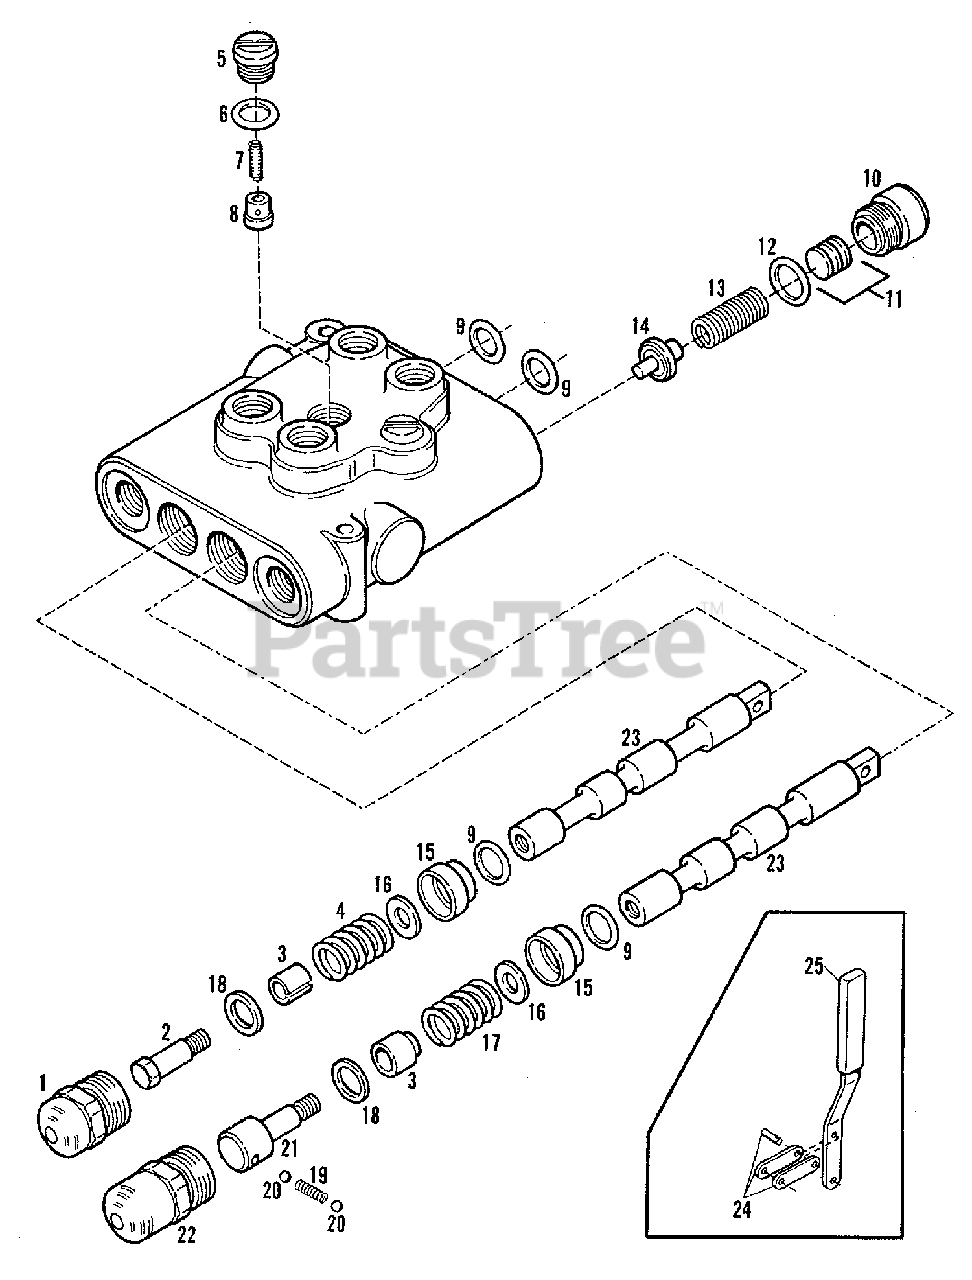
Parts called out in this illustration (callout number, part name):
2	SCREW, Spool
3	SPACER, Spool
4	SPRING, Spool Centering
5	PLUG ASSEMBLY, Lift Check
6	O-RING, Plug Assembly
7	SPRING, Lift Check Plug
8	PLUNGER, Lift Check Plug
9	O-RING, Spool
10	PLUG ASSEMBLY, Relief Valve
11	SHIM, Relief Valve
12	O-RING, Relief Valve Plug
13	SPRING, Relief Valve
14	POPPET, Relief Valve
15	BUSHING, Spool
16	WASHER, Spool
17	SPRING, Spool Centering
18	WASHER, Spool
19	SPRING, Detent
20	BALL, Detent Spring, 5/32 Diameter
21	SCREW, Detent
22	CAP ASSEMBLY, Detent Adapter
23	SPOOL
24	LINK ASSEMBLY, Valve
25	HANDLE ASSEMBLY, Valve
25	PIN, Cotter, 3/16 x 2
25	SEAL KIT, Valve O-Ring
